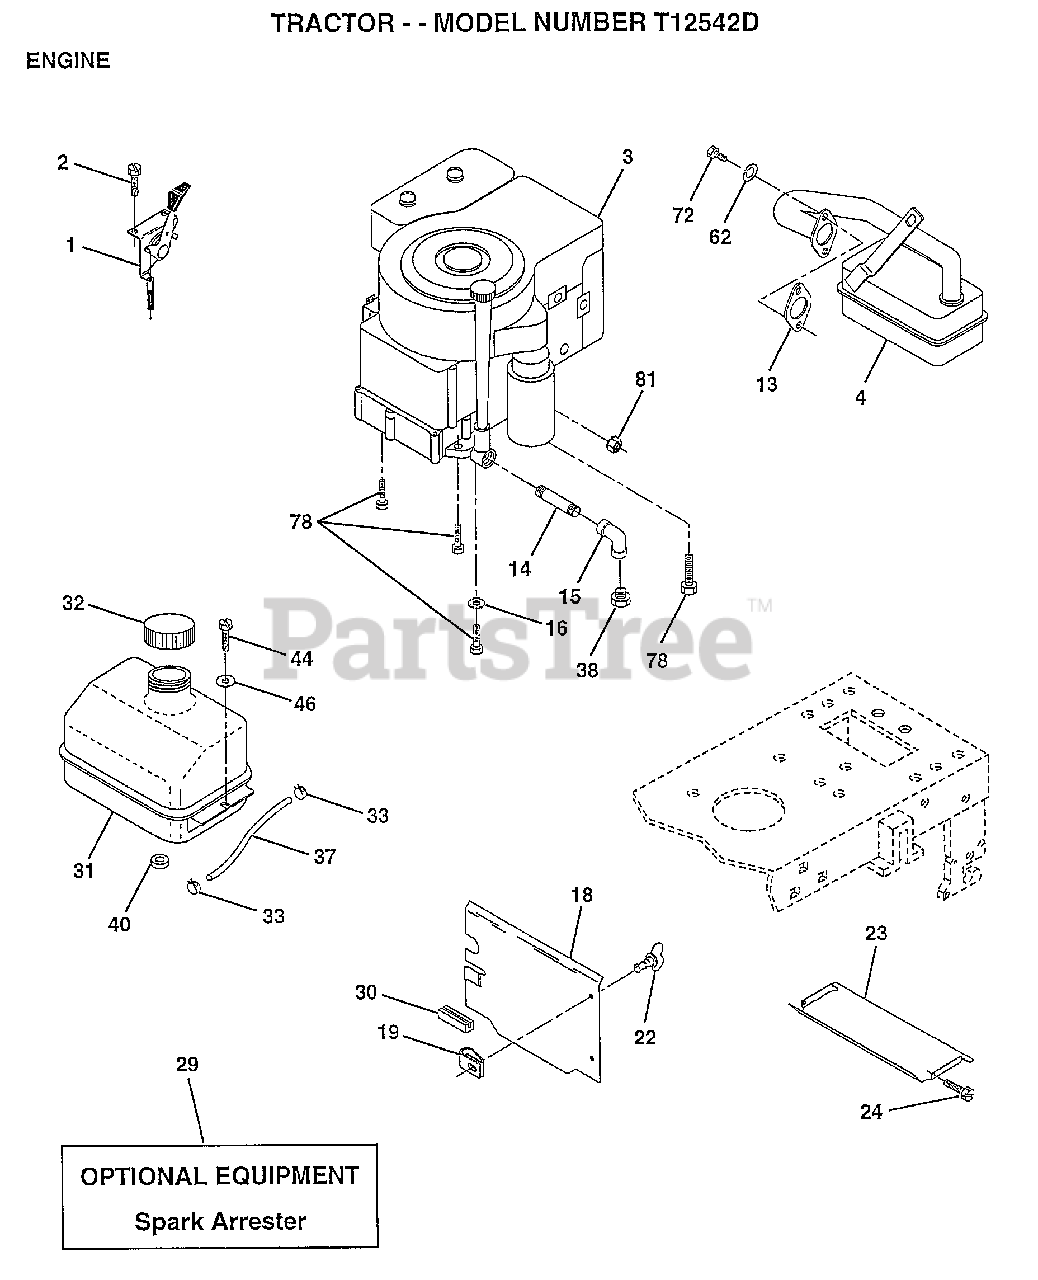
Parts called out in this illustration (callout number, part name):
1	CONTROL THROTTLE
2	SCREW LT
4	MUFFLER
13	GASKET ENG 1 313 LD TIN PLATED
14	PIPE NIPPLE
15	ELBOW
16	LOCKWASHER
18	SHIELD HEAT
19	RECEPTACLE LT
22	"STUD 1/4 TURN,BUS"
23	HEAT SHIELD
24	SCREW
31	TANK.FUEL.LT.
32	CAP ASM FUEL
33	HOSE CLAMP
37	LINE FUEL
44	SCREW HEX CRT
46	WASHER
62	LOCKWASHER
72	SCREW
78	SCREW
81	NUT
